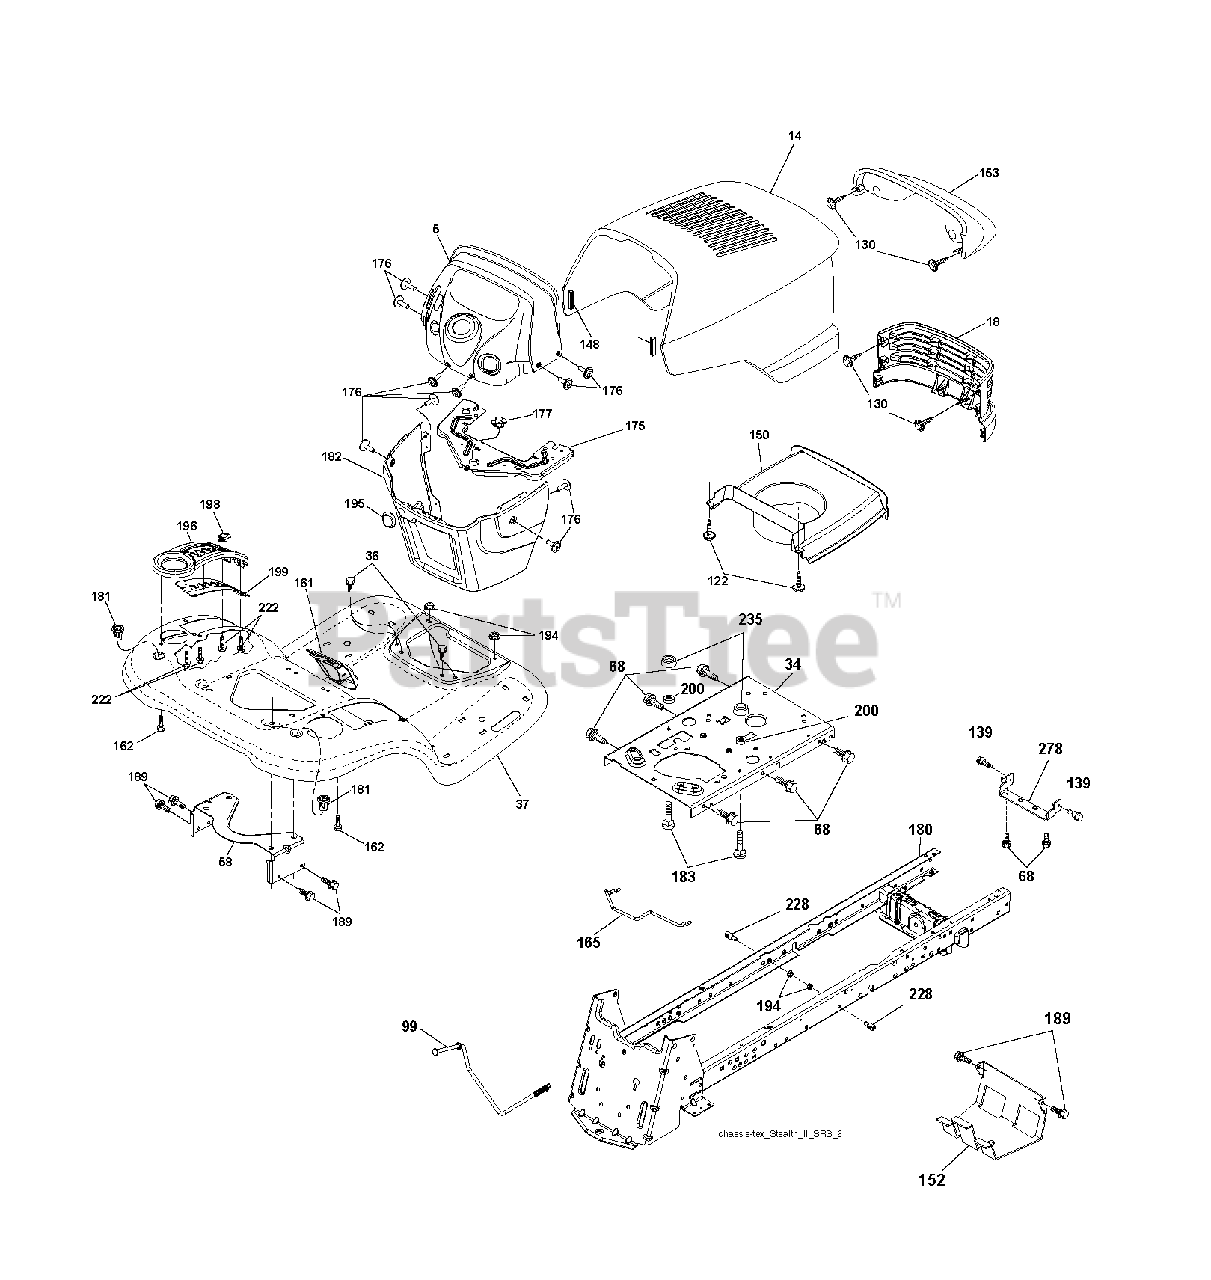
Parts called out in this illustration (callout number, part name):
5	DASH.UPR.STEALTH
34	PLATE.ENGINE.WELDED.CHASSIS
36	SCREW 5/16"
58	BRKT.SUPPORT.FNDR/TANK
99	ROD ASM BYPASS
122	SCREW.WSHD.HEX10-32X5/8
130	SCREW
139	BOLT, SHOULDER 5/16-18
148	EXTRUSION BUMPER
150	DUCT HOOD
152	SHIELD BROWNING
161	CONSOLE.FUEL.WINDOW.STGT.BLACK
162	SCREW.HI-LO.CONSOLE
165	SUPPORT.TANK.REAR.W/TE
175	CROSSMEMBER.
176	SCREW.#10-24X5/8.RN.QU
177	BUSHING,STEERING
180	CHASSIS.WLDMT.TX.GT.05
181	FEND/FTRST.PCH.CPH.NFW
182	DASH.LOWER.
183	BOLT.5/16-18X1-1/4 FULL.THREAD
189	SCREW
194	NUT LOCK HEX FLANGE 5/16-18
195	PLUG.HOLE.DASH.LOWER.12V.BLK
198	INDICATOR DECK LIFT
199	PLATE DECK LIFT
200	NUT.CENTERLOCK.5/16-
222	SCREW.1/4-20X5/8
228	STUD.FASTNER.W/ANTI-ROTATE
235	SPACER FENDER
278	BRKT.HOOD/MUFF.STEALTH
